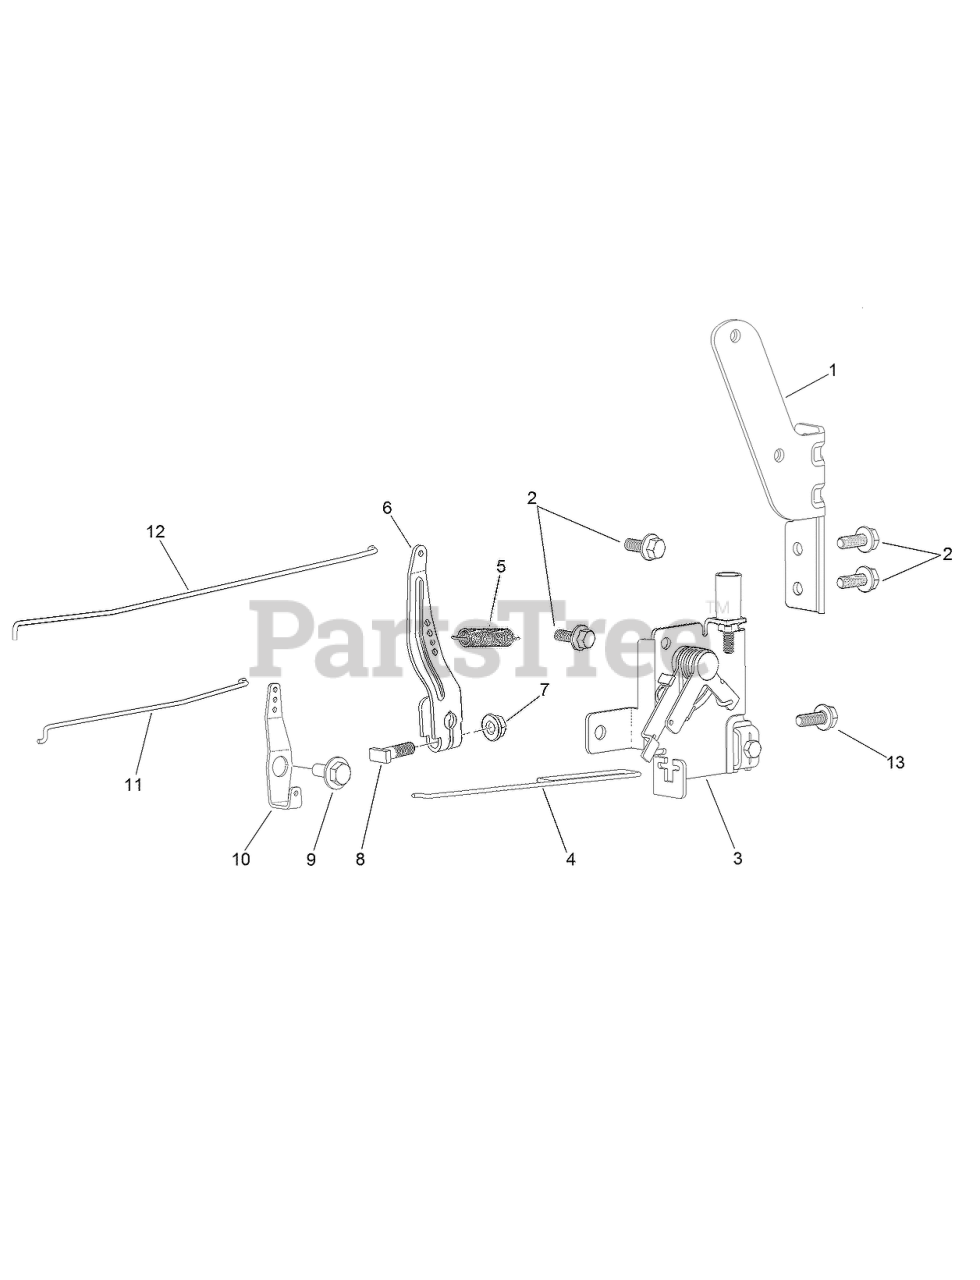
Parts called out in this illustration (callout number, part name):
1	BRACKET-PUMP, FUEL
2	SCREW-HHF
3	CONTROL-THROTTLE
4	ROD-THROTTLE
5	SPRING-GOVERNOR
6	ARM-GOVERNOR
7	NUT-FLANGE
8	BOLT-ARM, GOVERNOR
9	SCREW-SHOULDER, HHF
10	BELLCRANK-CHOKE
11	ROD-CHOKE
12	ROD-GOVERNOR
13	SCREW-HHF
